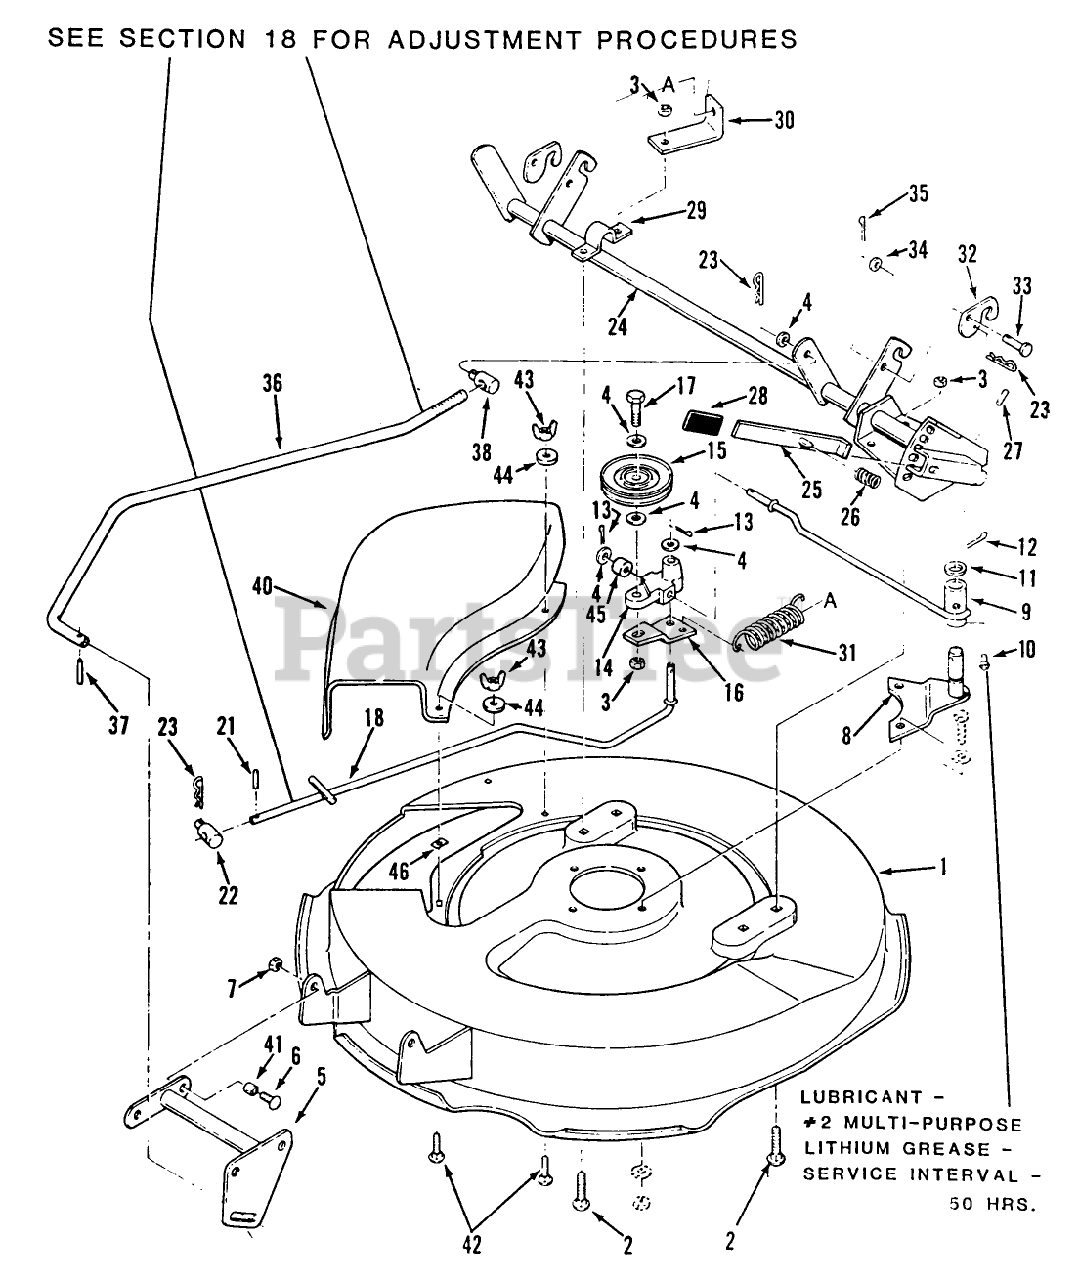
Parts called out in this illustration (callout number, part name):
5	ASM-FRONT LIFT *R
11	WASHER
14	BLOCK IDLER
15	PULLEY-IDLER V
22	TRUNNION-LIFT
23	Hairpin Cotter
25	LEVER ASSY
26	SPRING-COMPRESSION
27	PIN-SPIROL
29	CLAMP
31	SPRING-EXTENSION
36	ASS'Y-HEIGHT ADJ *R
37	SPIROL PIN
38	STUD-TRUNION
41	SPACER
44	WASHER
45	SPACER
46	SPEED NUT
